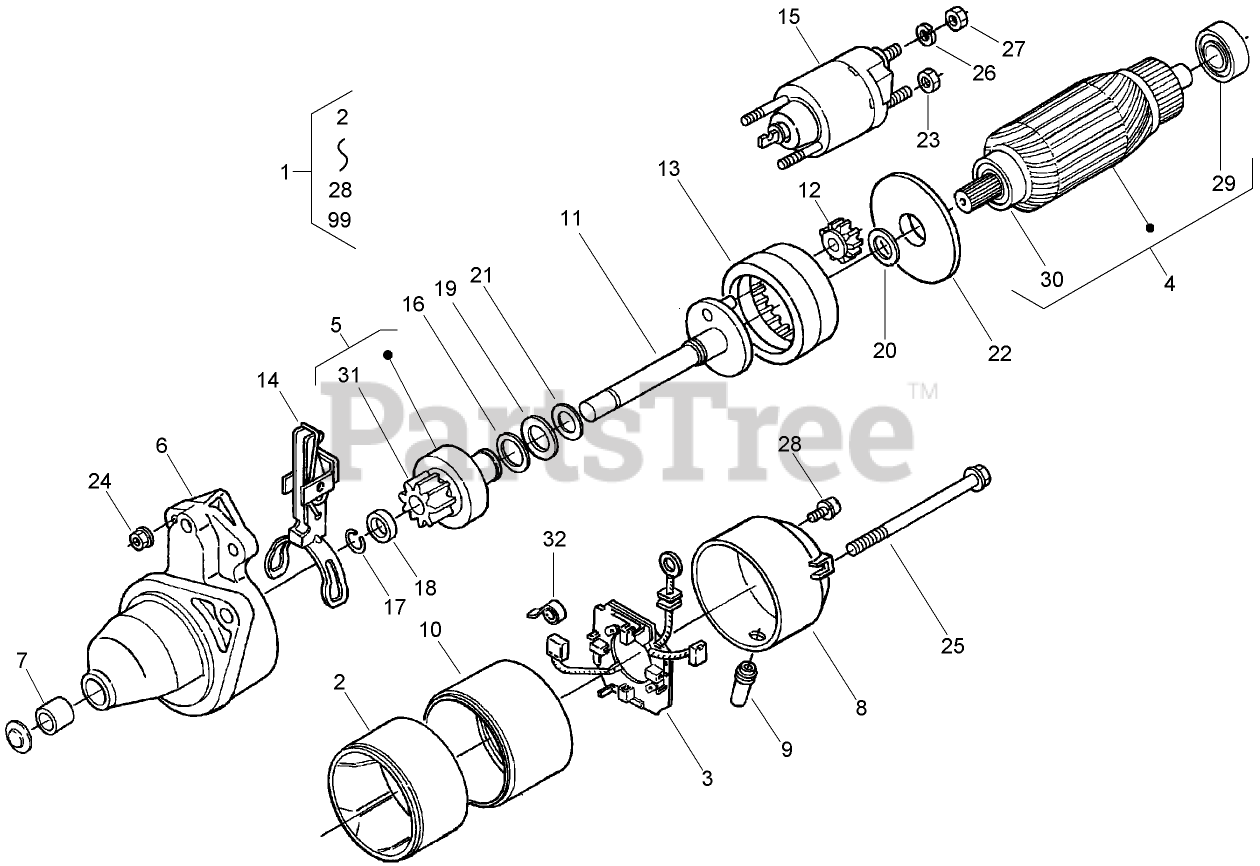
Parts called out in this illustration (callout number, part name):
1	STARTER ASM
2	STARTER YOKE ASM
3	HOLDER ASM
4	ARMATURE ASM
5	STARTER CLUTCH ASM
6	STARTER HOUSING ASM
7	BEARING
8	FRAME ASM
10	BEARING ASM
11	STARTER SHAFT ASM
15	MAGNETIC SWITCH ASM
16	RING-SNAP
17	RING-SNAP
18	COLLAR
19	WASHER-PLAIN
20	WASHER-PLAIN
21	WASHER-PLAIN
23	NUT-HEX
25	BOLT-THROUGH
26	WASHER-SPRING
27	NUT-HEX
29	BEARING-BALL
30	BEARING-BALL
31	GEAR-PINION
32	SPRING-BRUSH
99	WIRE-LEAD
